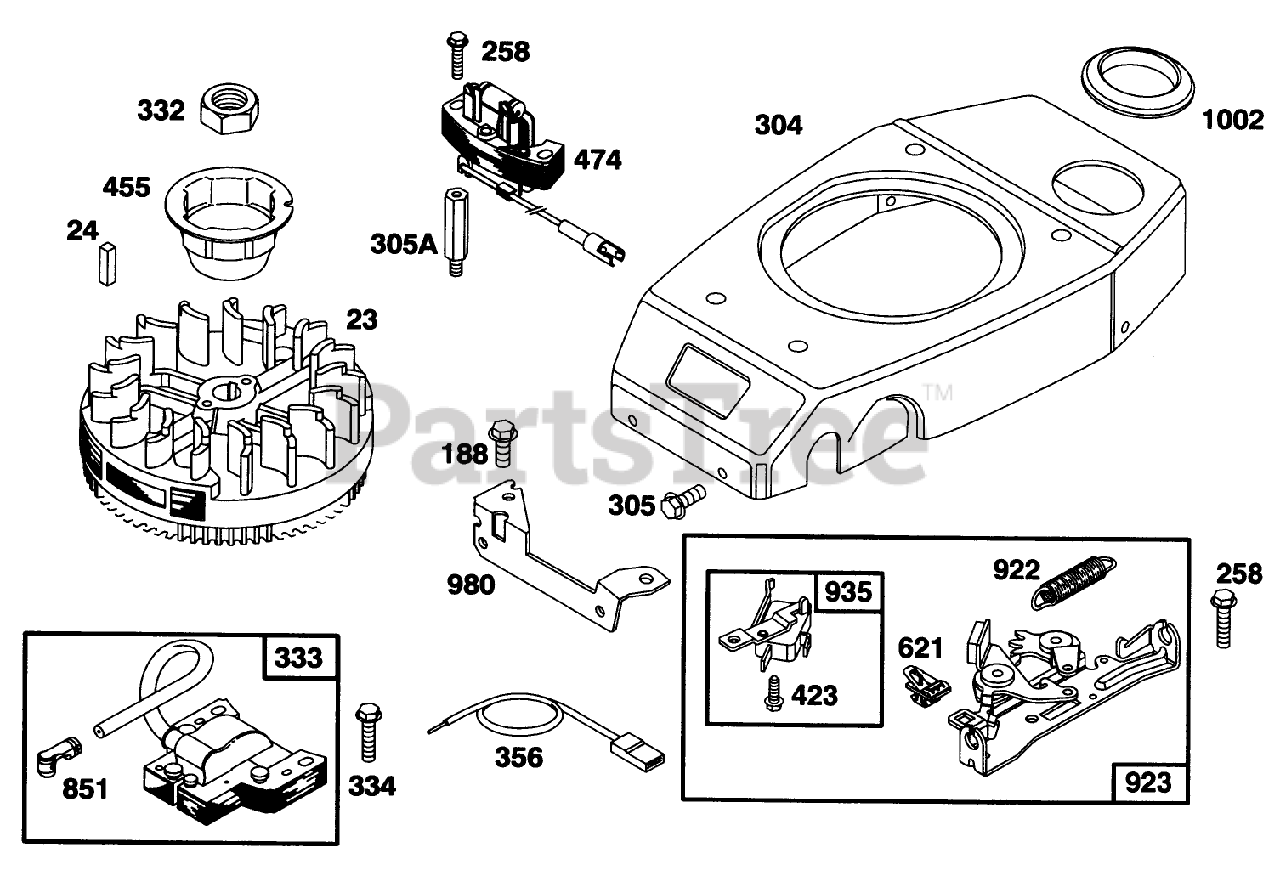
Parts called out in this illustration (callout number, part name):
23	FLYWHEEL - MAGNETO
24	KEY - FLYWHEEL
188	SCREW - HEX HEAD
305	SCREW - HEX HEAD
332	NUT-FLYWHEEL
356	WIRE - GROUND
455	CUP - STARTER
621	STOP SWITCH
980	BRACKET-BLOWER HSG
